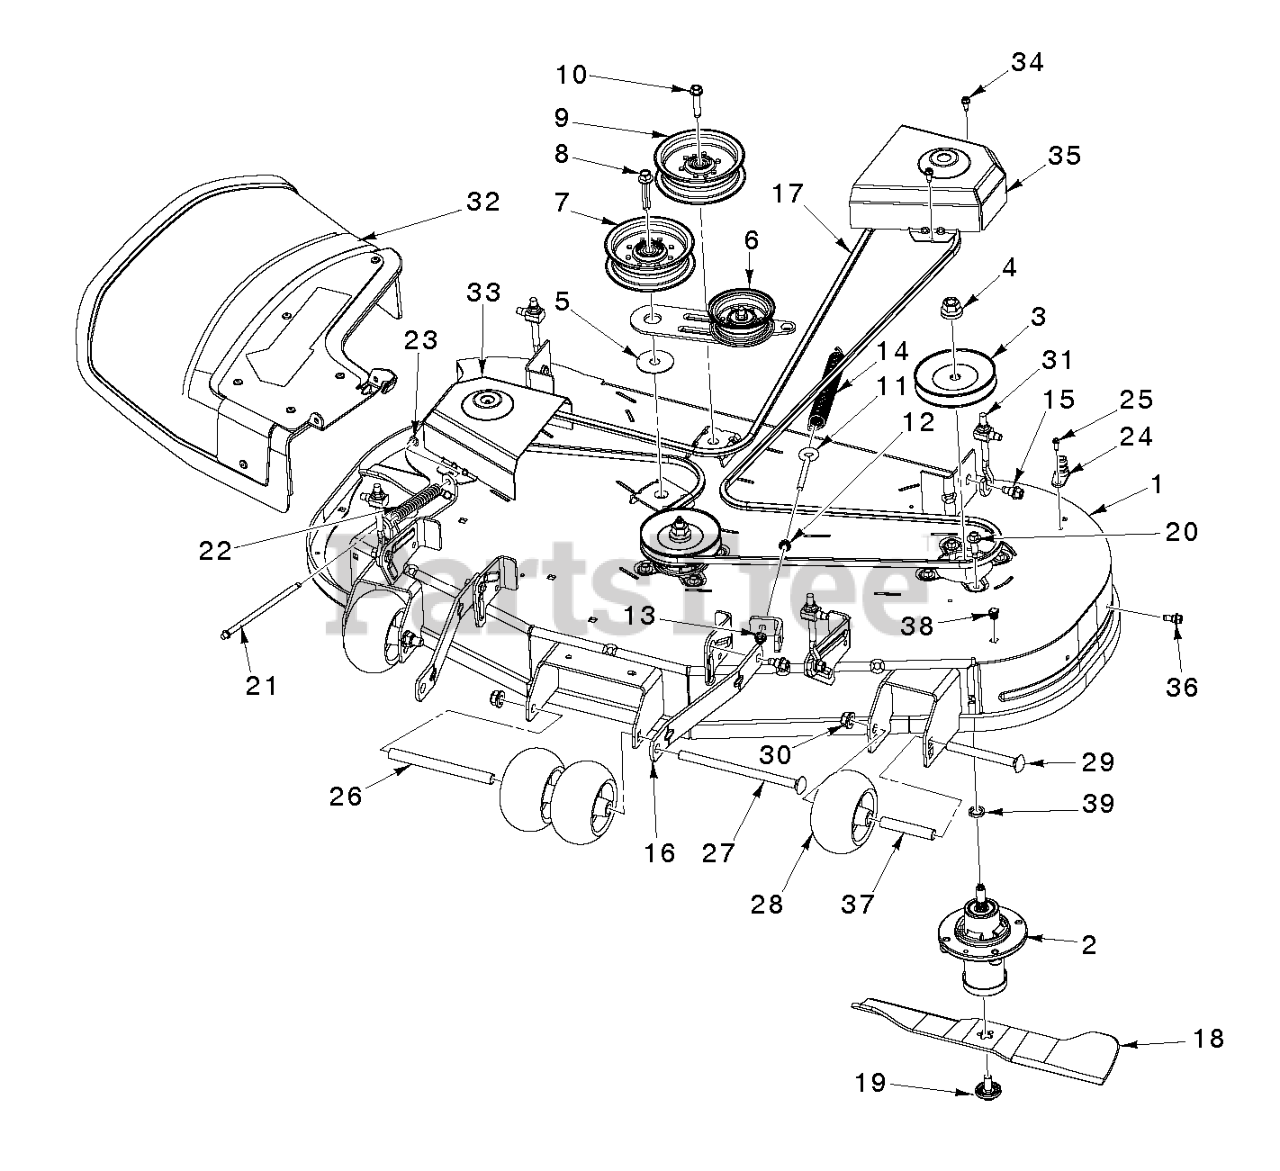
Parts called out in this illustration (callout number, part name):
2	MANDREL.DECK.ASSEMBLY
6	ARM.PNT.CLUTCHING.ASM.EDIP
7	PULLEY.IDLER.MWR.STATI.LH
8	SCREW.7/16-14 X 2.125.WASHER
9	PULLEY.IDLER.2006
10	BOLT;HEX_3/8-16 X 1.78.CLRZINC
11	GSPW Bolts
12	GSPW Hardware
13	NUT HEXAGON FLANGE 5/16-18 ST
14	SPRING.EXTENSION
15	BOLT.SHOULDER
16	ARM.RFIXED.MOWER.SUSPNSIONX431
18	BLADE.BAGGER.COM.CLRCT.48".BLK
19	BLADE BOLT/WASHER
20	BOLT.HEX.WASHR.HED.313-18X1.19
22	SPRING.42.FCS.DEFLECTOR
23	NUT PUSH M
24	PORT.WASHOUT
28	ROLLER, GAUGE .635 BORN
30	NUT 1/2-13 HEX FLANGE NYLOK CL
31	NUT.HEX.FLANGE.INS.BLK.3/8-16
31	LINK.ASM.ADJUSTABLE
32	GSPW Deflectors
33	COVER.PNT.MANDREL.RH.GREY
34	SCREW.1/4-20X5/8
35	COVER.PNT.MANDREL.LH.ZTR.GREY
36	BOLT.5/16HEX.WHS.HD
